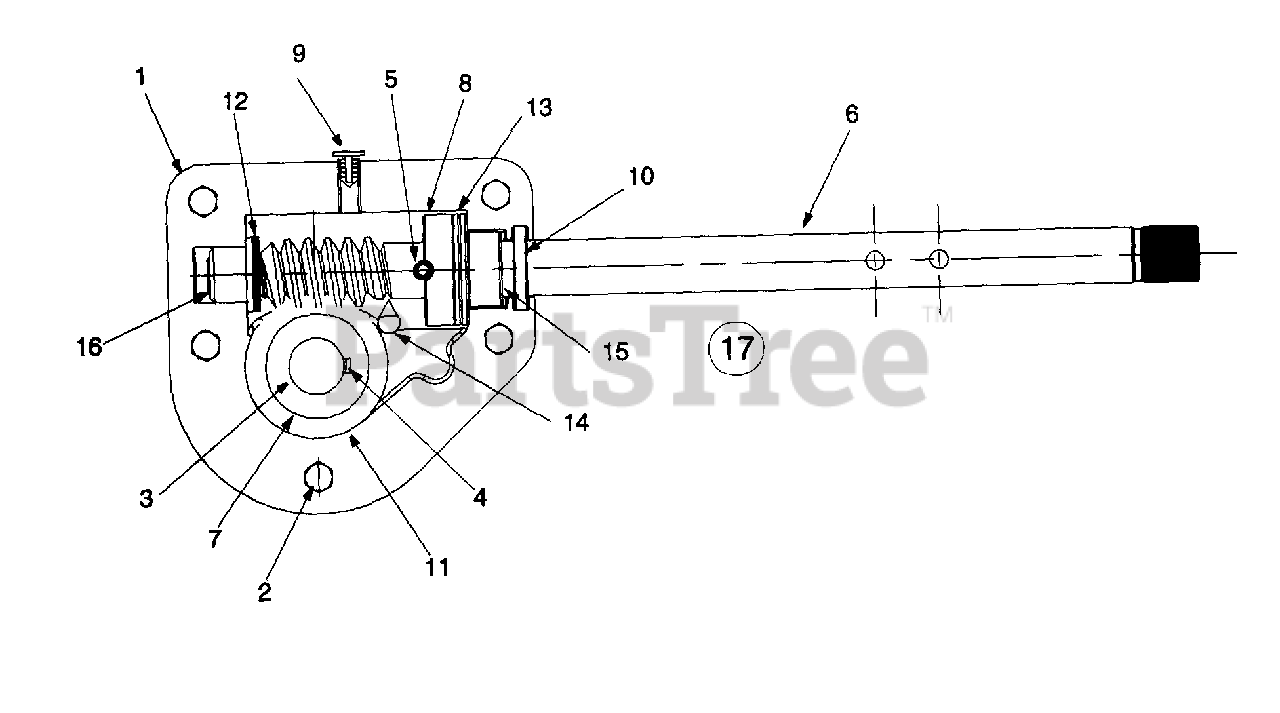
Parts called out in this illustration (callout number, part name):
1	Housing - L.H.
2	Hex Screw 1/4-20 x .75
3	Spiral Axle 24"
4	Key
5	Pin-Spiral
6	Shaft-Worm
7	Gear-Worm
8	Collar-Thrust
10	Seal-Oil
11	Washer-Flat
12	Washer-Flat
13	Washer-Flat
14	Grease
15	Bearing-Flange
16	Bearing-Flange
17	Ass'y. Complete 24"
